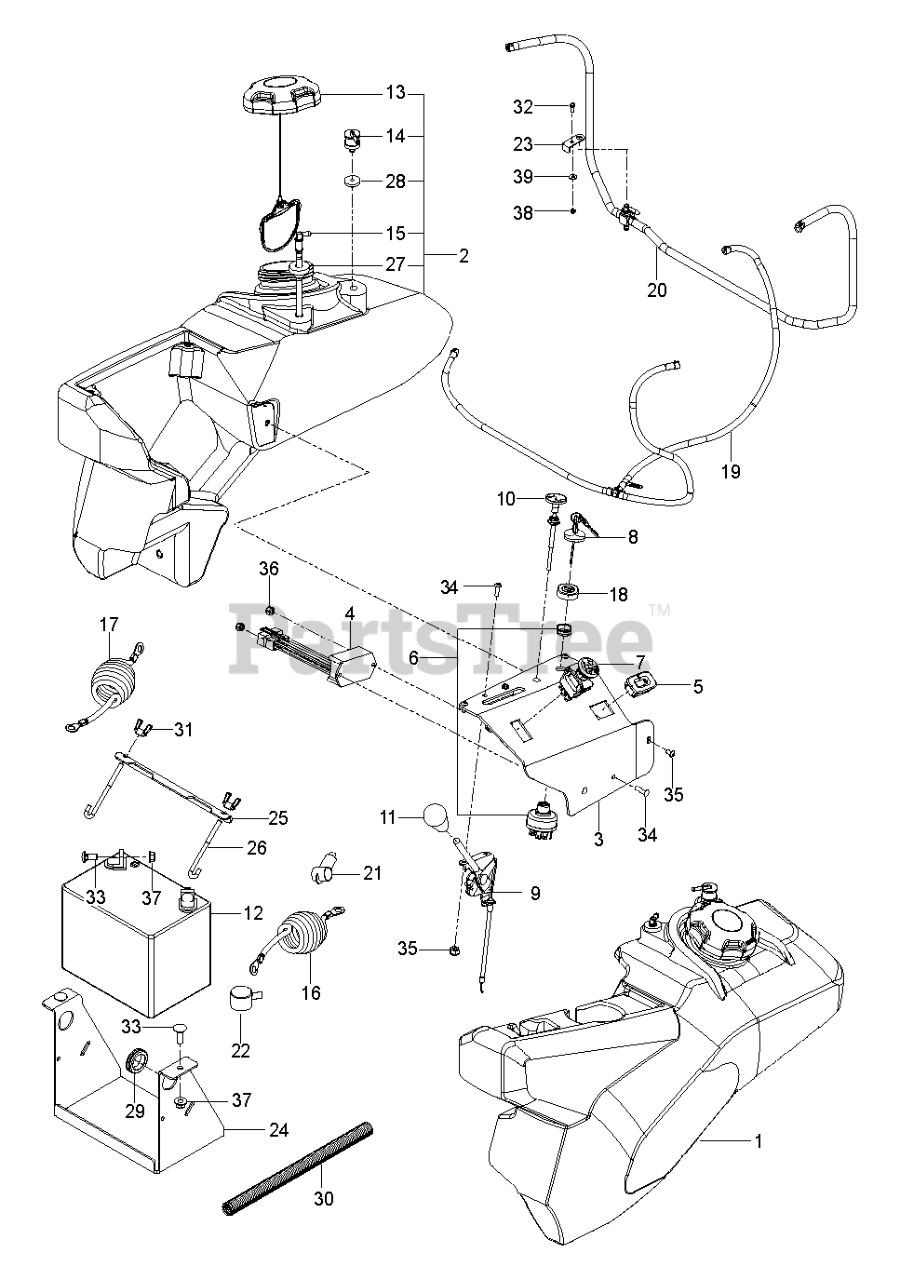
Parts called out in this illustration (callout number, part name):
1	FUEL.TANK.ASM.LH.PZ.GRY.17
2	FUEL.TANK.ASM.RH.PZ.GRY.17
3	PANEL.CONTROL.GAS.GRAY
4	TIMER, SEAT
5	GUAGE.SRVCMNDR.HRMTR.
6	SWITCH, IGNITION, INDAK
7	RP SWITCH.PTO.TERMINAL.STD.RED
8	KEY, IGNITION
9	CABLE, THROTTLE, 46"
10	CABLE, CHOKE, 48"
11	KNOB - SHIFT
12	BATTERY, 12 V 330 AMP
13	CAP, FUEL
14	VALVE.FUEL.CHECK
15	FITTING, FUEL
16	CABLE, POSITIVE, 55"
17	CABLE, NEG, 55"
18	CAP IGNITION NUT
19	HOSE.ASM.VAPOR.LINE.21-30-39
20	ASSEMBLY, FUEL LINE
22	LOOM SPLIT 5/8, 32"
23	BRACKET.VALVE.PNT.BLACK.X431
24	BRACKET, BATTERY, BLK
25	BRACKET.BATTERY.MOUNT.PLATED
27	RUBBER GROMMET
28	GROMMET, CHECK VALVE
29	RUBBER GROMMET
30	COVER.TERMINAL.BATTERY
31	WING NUT 1/4
32	HCS 1/4C X 3/4 HCS
33	RP BOLT 5/16-18 X3/4 ZN/YEL GR
34	SCR #10-24 X .75 SKT HD BLK
35	SCR #10-24 X 3/8 SKT HD BLK OX
36	NUT 10-24 NYLOC
37	5/16-18 NYLOC FLANGE NUT
38	JAM NUT 1/4C (2 2 PW01)
39	WASHER 1/4 FLAT
